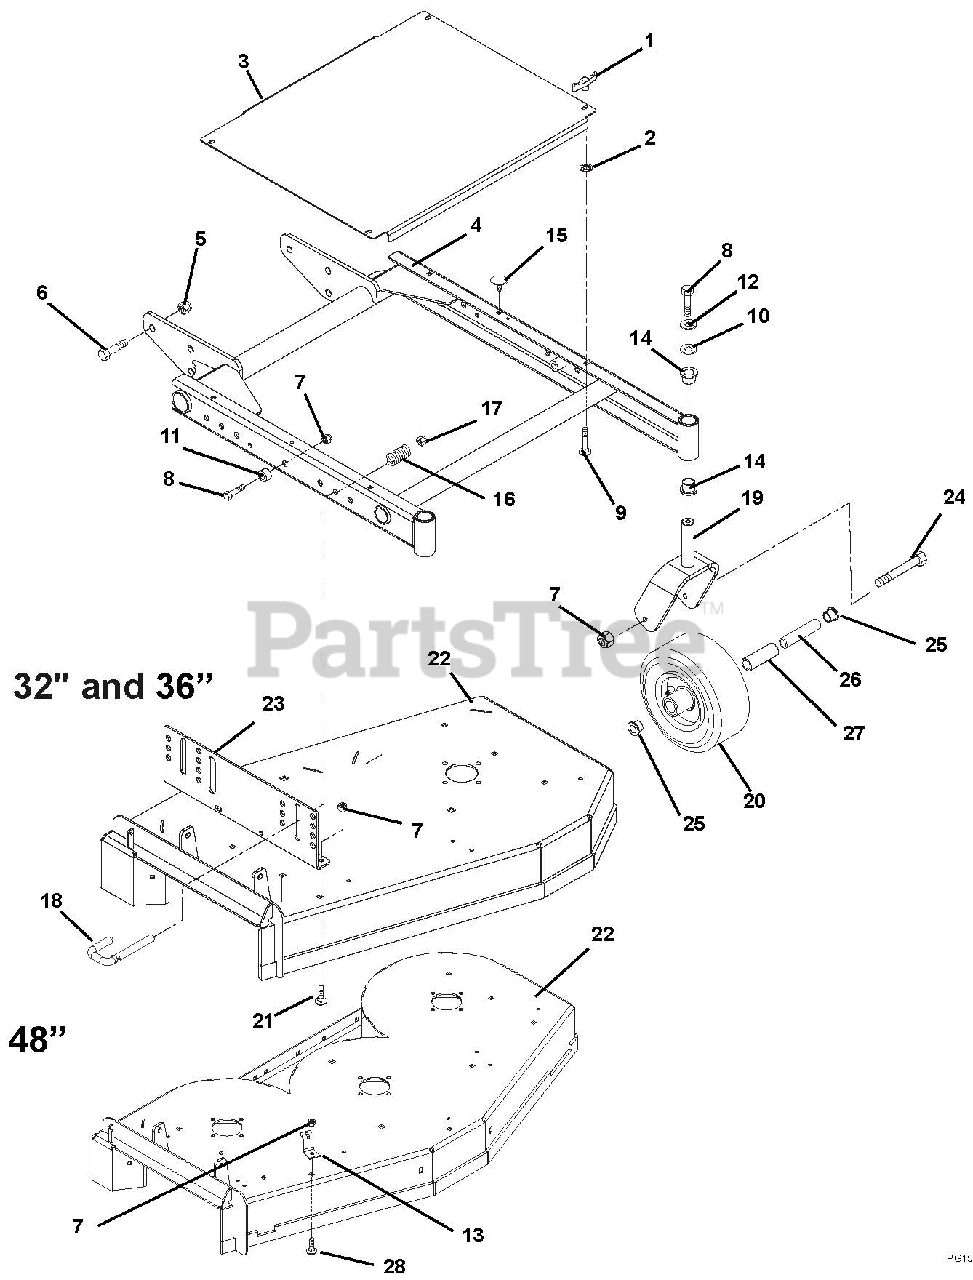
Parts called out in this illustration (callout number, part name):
1	Knob- Wing .312-18
2	Nut-Push .312
3	Cover, Belt Pro Mower
3	Cover, Belt Pro Mower - 32"
4	Weldment - Mower Frame 36"
4	Weldment - Mower Frame 48"
4	Weldment - Mower Frame 32"
5	Nut-Locking-Nylon .625-11
6	Bolt-Hex .62-11 x 1.50
7	Nut-Locking-Top-Flange .38-16
8	Bolt-Hex .38-16 x 1.25 Grade 5
9	Bolt-Round Head Square Neck .31-18 x 1.00
10	Washer-Flat-Steel .38 x 1.50 x .125
12	Washer-Locking .38 x .094 Regular
13	Anchor, Spring
14	Bushing-Flange 1.00 x 1.25 x 1.50 x 1.50
15	Bumper Grommet .125 x .25 Dia.
16	Spring-Compression .058 x .65 x 2.13
17	Nut-Locking-Center .50-13
18	Pin- Latch
19	Weldment-Caster Fork
20	Wheel 9 x 3.50
21	Bolt-Round Head Square Neck .38-16 x 1.00 Grade 5
22	Kit, 32" Fixed Mower Deck with Decals
22	Kit, 36" Fixed Mower Deck with Decals
22	Kit, 48" Fixed Mower Deck with Decals
23	Kit-Mower Side Support Bracket-Right Hand and Left Hand
24	Bolt-Hex .38-16 x 5.50
25	Bearing-Retainer
26	Bearing .625 x .380 x 4.08
27	Bearing-Roller
28	Bolt-Round Head Square Neck .38-16 x .75 Grade 5
